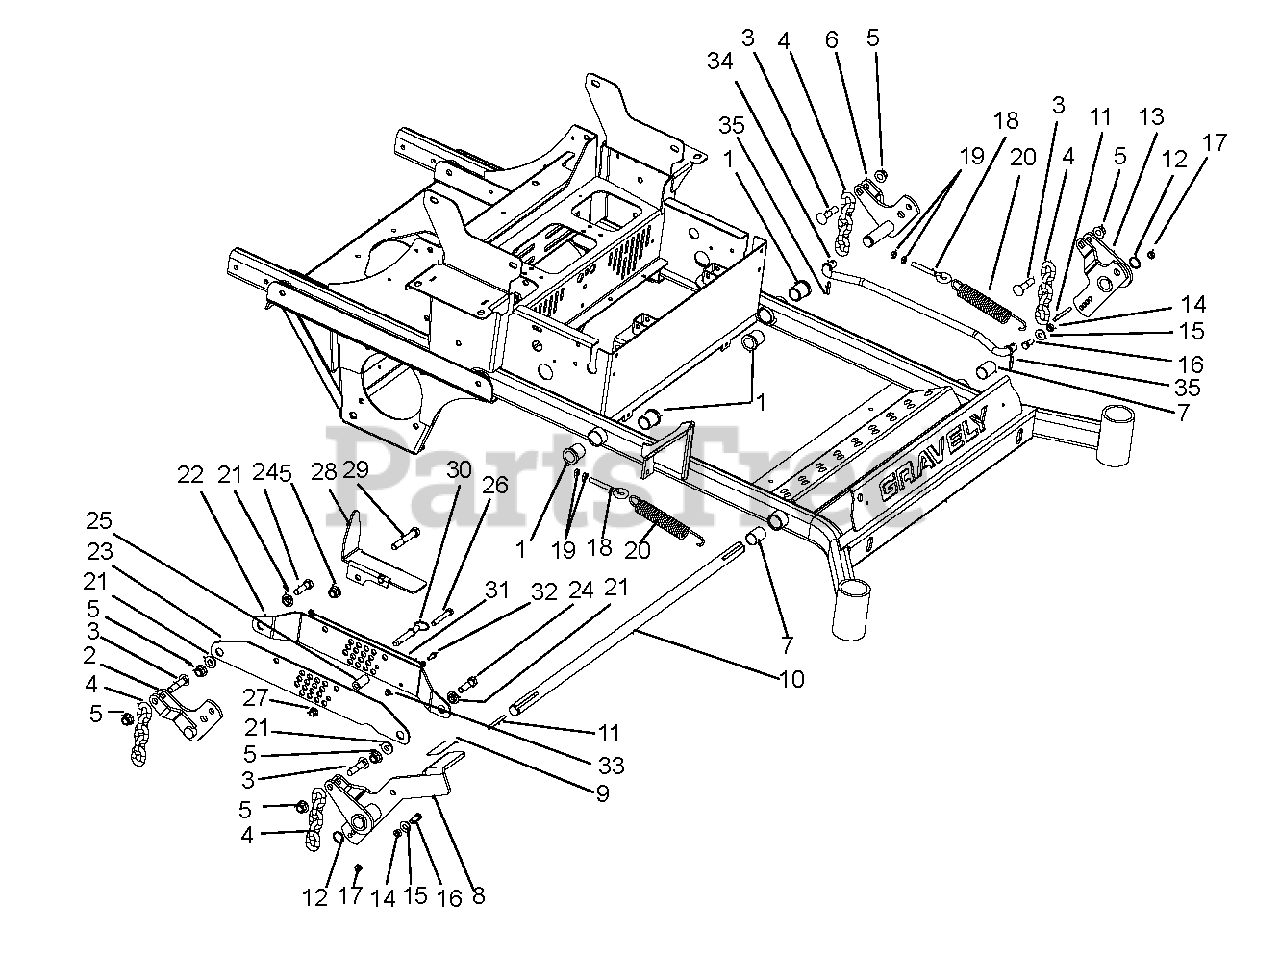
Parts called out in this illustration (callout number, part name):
1	Bushing, Flange 1.00 x 1.25 x 1.50 x 1.50
2	Weldment, Right Hand Rear Deck Lift
3	Bolt-Round Head Square Neck .50-13 x 2.25 G5YZ
4	Chain, 5 Link 3/8 Mower Lift
5	Nut, Locking Nylon-Flange .50-13
6	Weldment, Left Hand Rear Deck Lift
7	Bushing,1.00ID x 1.125OD x 1.50LG
8	Weldment, Deck Foot Lift
9	Grip Pedal 1.50 x 3.00
10	Shaft, Front Mower Lift
11	Key-SQ .25 x 2.50 x .25 SAE
12	Ring, Retaining-E x T 1.00 x .078
13	Weldment, Front Left Hand Deck Lift
14	Bushing, Sleave .377 x .624 x .235
15	Washer, Flat Steel.438 x 1.00 x .083
16	Bolt, Hex .38-16 x 1.00 GR5
17	Nut, Locking Center-JAM .375-16
18	Bolt, Eye .375-16 x 2.50
19	Nut, Hex-JAM .375-16
20	Spring, Tension .162 x 1.25 x 8.25 WLD 25
21	Bushing, Flange .515 x .750 x .395 x 1.120
22	Bracket, Right Hand Lift/Cut Height Inboard
23	Bracket, Right Hand Lift/Cut Height Outboard
24	Bolt, Hex .50-13 x 1.75 GR5
25	Spacer, .375 x .750 x 1.54
26	Bolt, Hex .38-16 x 2.50 GR5
27	Nut, Locking Nylon-Flange .38-16
28	Weldment, Mechnical Lock-Up
29	Bolt, Hex .50-13 x 3.25 GR5
30	Pin, .50 x 2.00
31	Cable, 12.0 Lanyard, Nylon
32	Bolt, Hex .25-20 x .75 GR5
33	Nut, Locking Nylon-Flange .25-20
34	Rod, Lift Assist 19.35"
35	Pin, Roll .250 x 1.25 Stainless Steel
